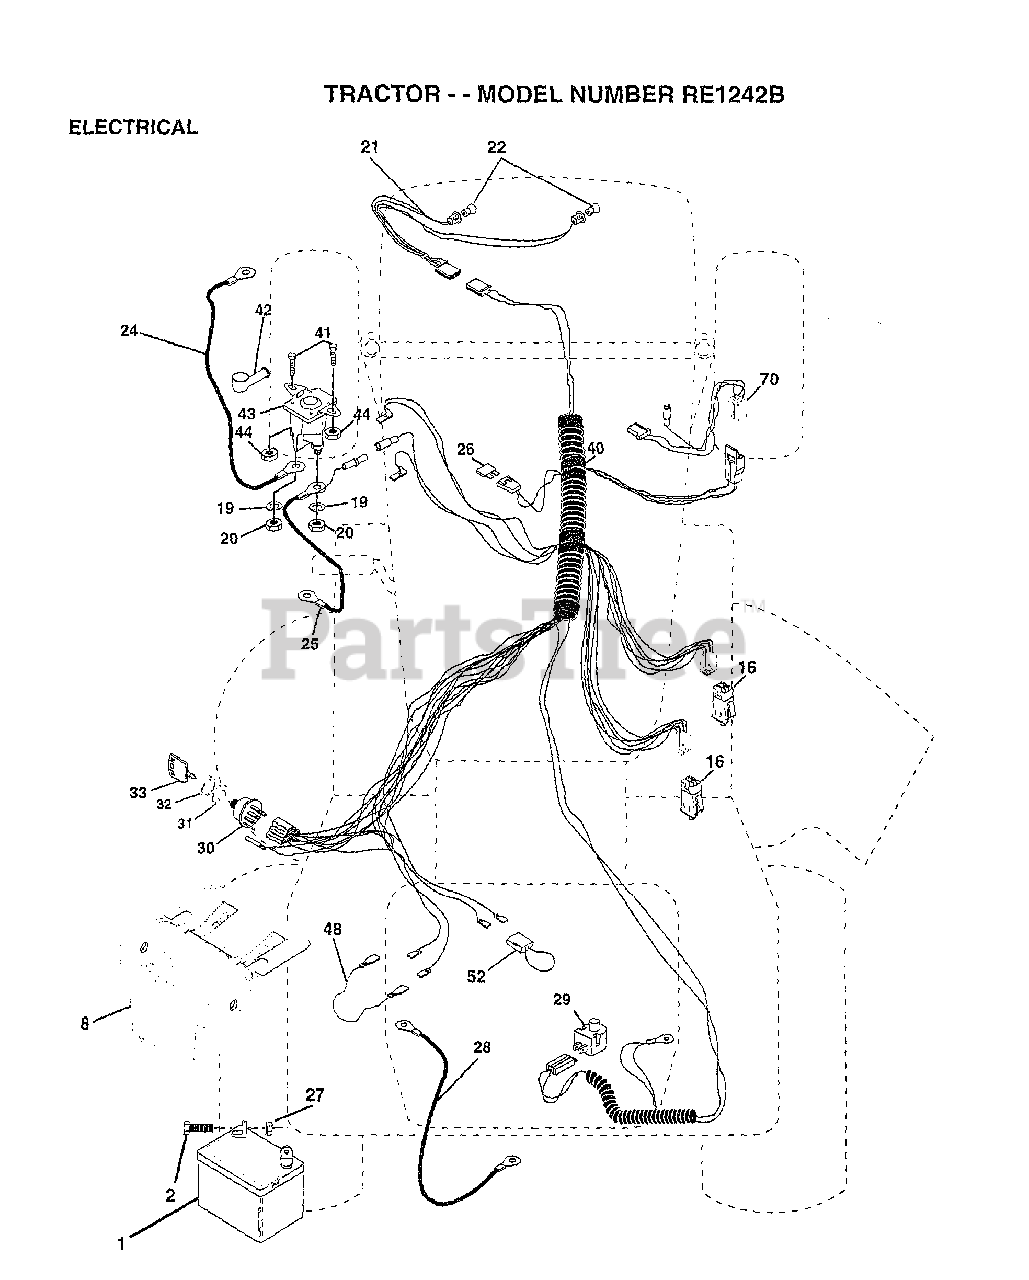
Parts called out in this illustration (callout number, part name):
2	BOLT LT
8	"CASE,BATTERY.MECH"
16	SWITCH INTERLOCK
20	NUT
21	HARNESS.ASM.LIGHT W/4152J
22	HEADLAMP BULB
24	"CABLE T, BATTERY"
25	CABLE.BTRY.6GA.RD
26	FUSE.15 AMP
27	NUT
28	CABLE T
29	SWITCH SEAT
30	SWITCH IGN 4POS
31	NUT IGNITION
32	COVER KEY SWITCH
33	KEY
40	HARNESS.IGNITION
41	BOLT HXHD FIN
44	NUT HXKEP 1/4X20
48	ADAPTER AMMETER
52	PROTECTION LOOP
70	HARNESS.ENGINE
